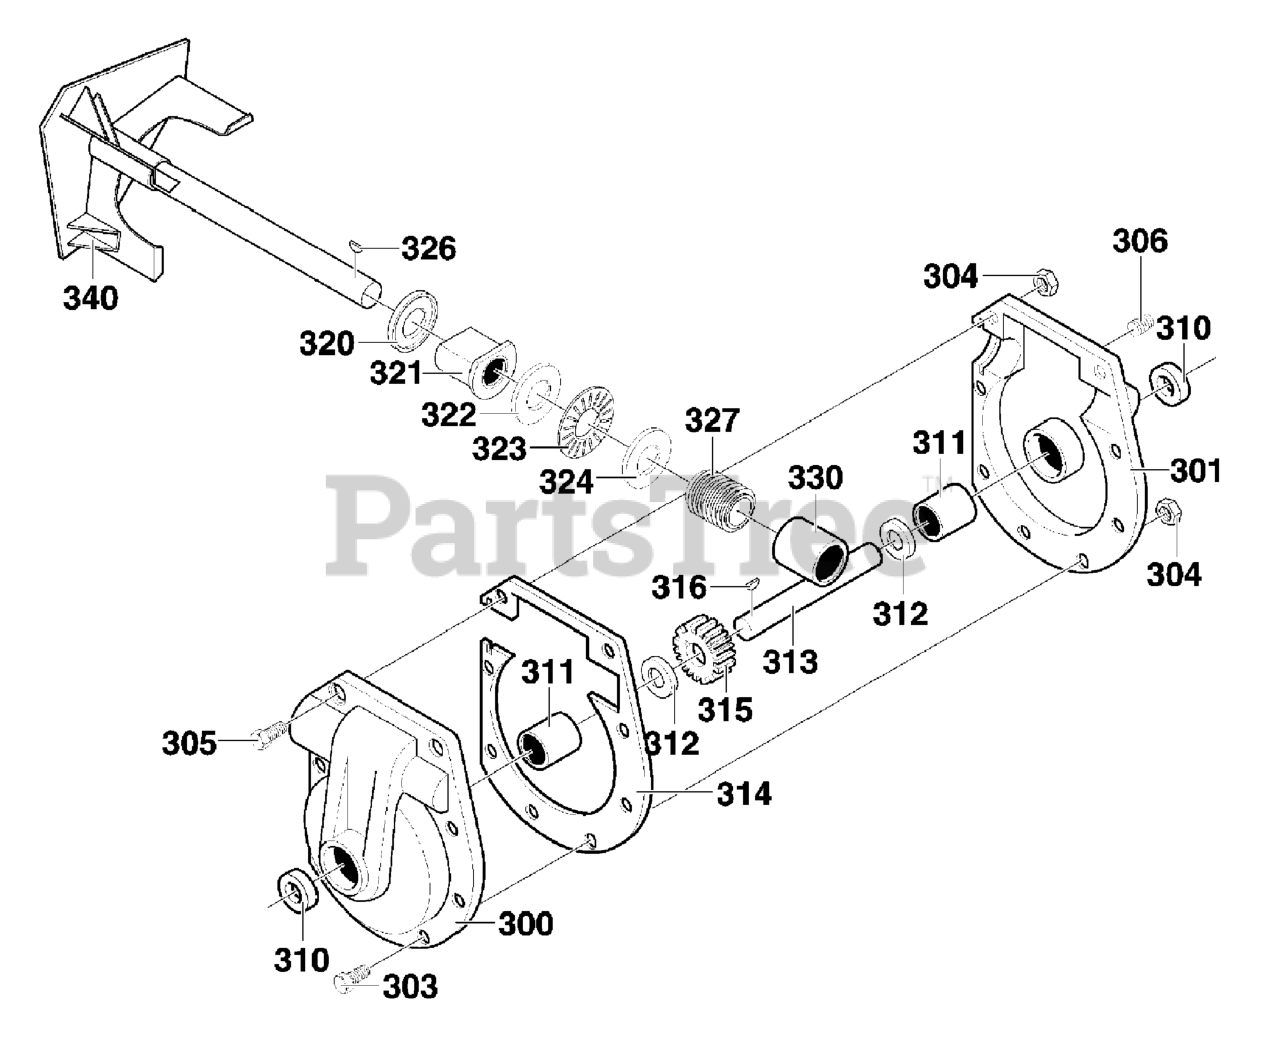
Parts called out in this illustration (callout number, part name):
300	CASE, GEAR, RH
301	CASE, GEAR, LH
303	SCREW, 5/16-24 x 1.00
304	NUT, 5/16-24
305	SCREW, 5/16-24 x 1.50
306	PLUG, PIPE
310	SEAL, OIL
311	BEARING
312	WASHER, FLAT
313	SHAFT, AUGER OUTPUT
314	GASKET, GEAR BOX
315	WORM GEAR
316	KEY, WOODRUFF #61
320	RING, QUAD
321	BEARING, FLANGE
322	WASHER, FLANGE
323	BEARING, ROLLER
324	WASHER, FLAT
327	GEAR, WORM
330	BEARING
340	IMPELLER
